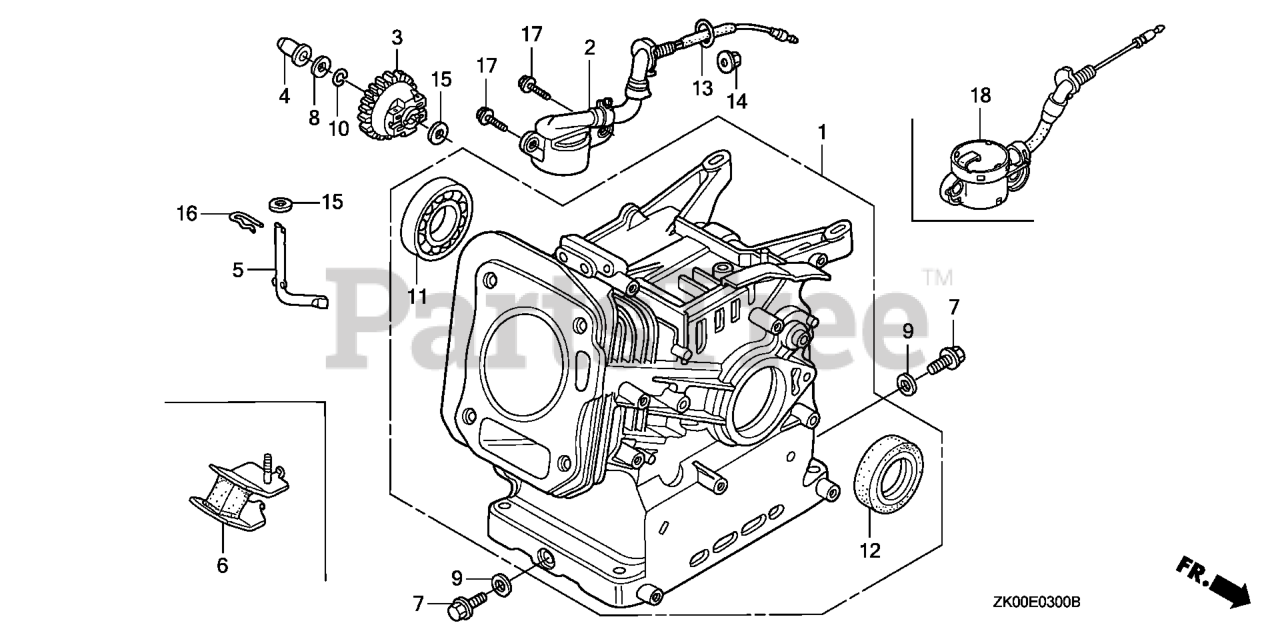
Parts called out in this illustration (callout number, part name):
1	CYLINDER ASSY.
2	SWITCH ASSY., OIL LEVEL
3	GOVERNOR ASSY.
4	SLIDER, GOVERNOR
5	SHAFT, GOVERNOR ARM
7	BOLT, DRAIN PLUG
8	WASHER, THRUST (6MM)
9	WASHER, DRAIN PLUG (10.2MM)
10	CLIP, GOVERNOR HOLDER
11	BEARING, RADIAL BALL (6205)
12	OIL SEAL (25X41X6)
13	O-RING (14MM) (ARAI) Use up to Engine SN 2949254.
14	NUT, FLANGE (10MM)
15	WASHER, PLAIN (6MM)
16	PIN, LOCK (8MM)
17	BOLT, FLANGE (6X12) Use up to Engine SN 1543277.
